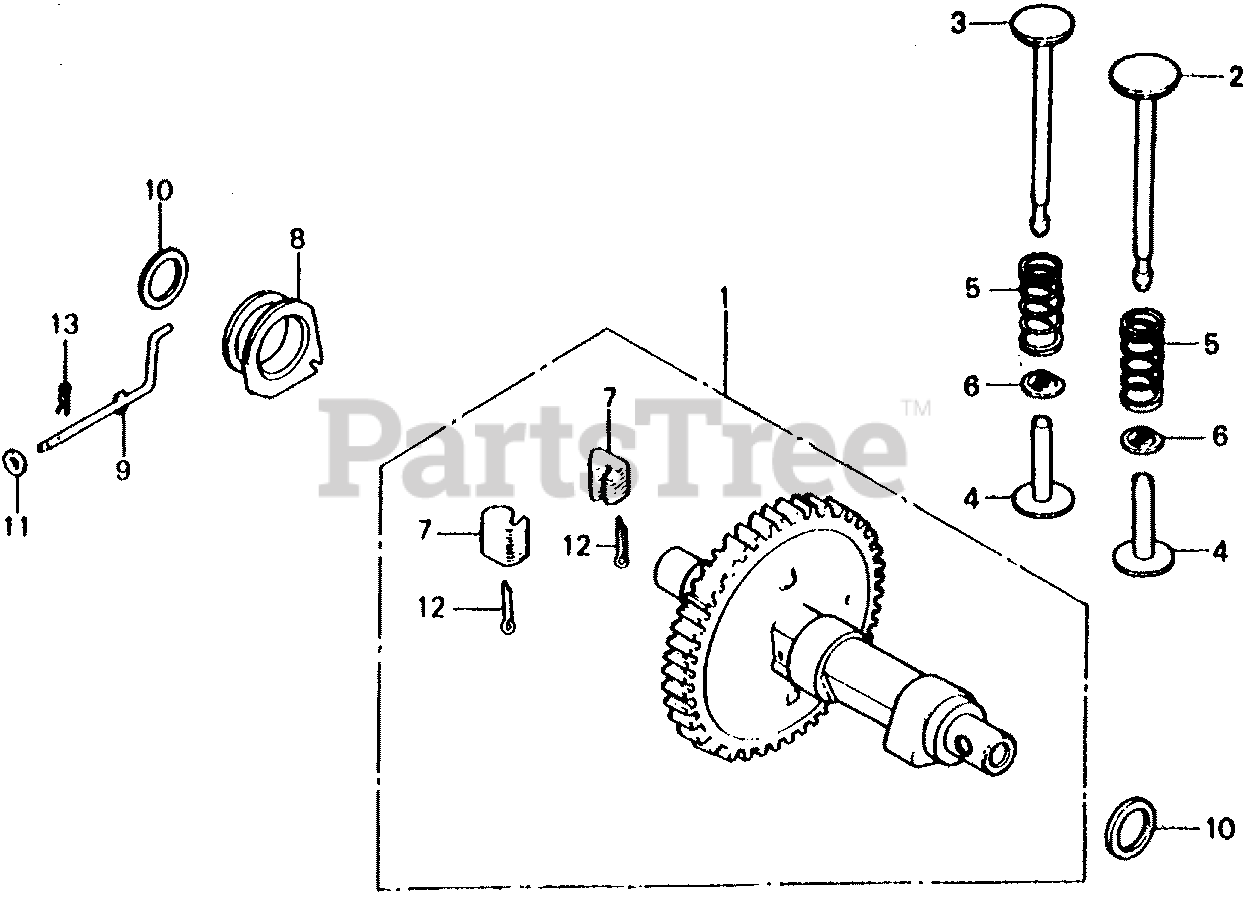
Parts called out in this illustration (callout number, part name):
1	CAMSHAFT ASSY.
2	VALVE, IN.
3	VALVE, EX.
4	LIFTER, VALVE (39.6MM)
4	LIFTER, VALVE (39.9MM)
5	SPRING, VALVE
6	RETAINER, VALVE SPRING
7	WEIGHT, GOVERNOR
8	SLIDER, GOVERNOR
9	SHAFT, GOVERNOR ARM
10	WASHER, THRUST (18MM)
11	WASHER, PLAIN (5MM)
12	PIN, COTTER (3.0X45)
13	PIN, LOCK (8MM)
